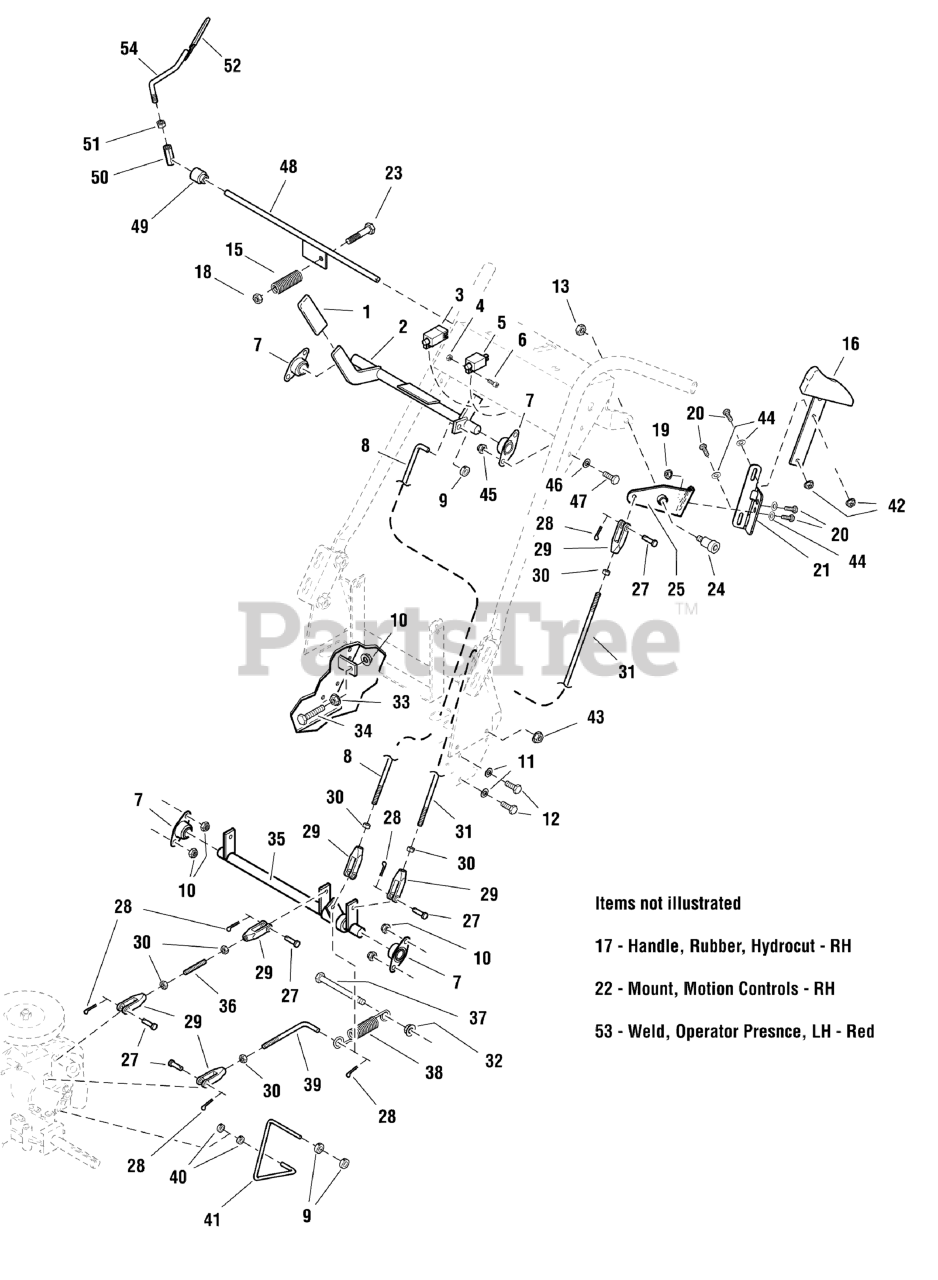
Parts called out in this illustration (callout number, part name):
1	GRIP, FOAM, 1/4 X 1 X 4.1
2	WELD, BRAKE CONTROL
3	SWITCH, Plunger, NO/NO
4	NUT, #10-24 HEX
5	SWITCH, PLUNGER, N.C.
6	SCREW, #10-24 X 1/2" ROUND PHILLIPS
7	BEARING, BRONZE FLANGE, 3/4
8	ROD, PARKING BRAKE LINKAGE
9	COLLAR, 5/16" SET
10	NUT, 5/16-18 HEX NYLOCK FLANGE
11	WASHER, 5/16" SAE
12	BOLT, 5/16-18 X 3/4 GD5
13	NUT, 3/8-16 HEX TOP LOCK
14	GRIP, VINYL, 1/2 X 4
15	SPRING, COMPRESSION
16	HANDLE, RUBBER HYDROCUT - LH
18	NUT, 1/4-20 HEX NYLOCK FLANGE
19	NUT, 1/4-20 HEX SERR. FLANGE
20	BOLT, 1/4-20 X 3/4" GD5 YZ
21	MOUNT, MOTION CONTROLS - LH
23	BOLT, 1/4-20 X 3" GD5 YZ
24	BOLT, 3/8-16 X 1.0", 1/2" SHOULDER
25	WELD, ARM CONTROL, LH
27	PIN, CLEVIS, 5/16" X 1
28	PIN, 3/32 X 0.750, COT, ZINC/CLEAR
29	CLEVIS, 5/16-24, PLASTIC
30	NUT, 5/16-24 HEX
31	ROD, THUMB CONTROL LINKAGE
32	NUT, 3/8-16 HEX SERRATED FLANGE
33	NUT, 5/16-18 HEX SERRATED FLANGE (LARGE)
34	BOLT, 5/16-18 X 1 1/2" FLANGE
35	WELD, CONTROL SHAFT
36	LINK, STUD
37	BOLT, 3/8-16 X 4" GD5 CZ
38	SPRING, EXT, 3.875 X .70 LOOP
39	LINK, PARKING BRAKE LOWER
40	COLLAR, 1/4" SET
41	LEVER, DUMP VALVE
42	NUT, 1/4-20 HEX NYLOCK FLANGE
43	NUT, 3/8-16 HEX NYLOCK FLANGE
44	WASHER, 1/4 SAE
45	NUT, 3/8"-16 HEX NYLOCK FLANGE
46	WASHER, 3/8 SAE
47	BOLT, 3/8-16 X 3/4" GD5 CZ
48	ROD, OPC SWITCH, SPACER
49	SPACER, SHOULDER
50	ADJUSTER, LINKAGE
51	NUT, 3/8-16 HEX
52	ASSM, OPERATOR PRESENCE, RH - RED
53	ASSM, OPERATOR PRESENCE, LH - RED
